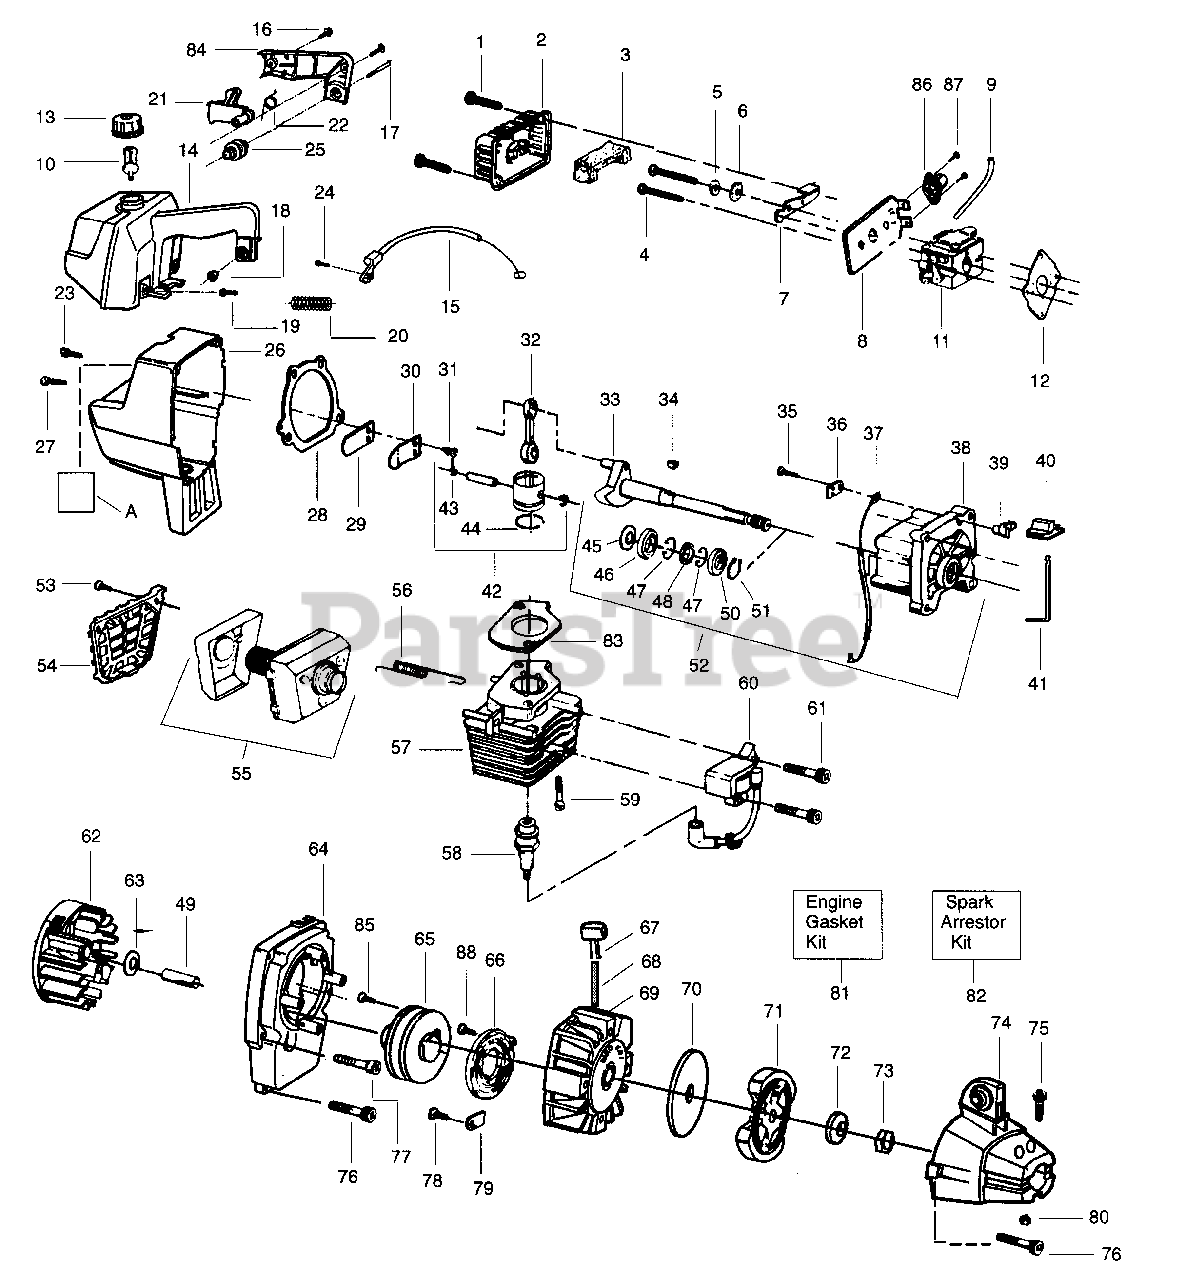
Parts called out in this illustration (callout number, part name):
2	Air Filter Cover
3	Air Filter
6	Wave Washer
7	Choke Shutter
8	MODEL GTI 19
8	MODEL GTI 19T Type 2 & 3
9	Fuel Line
9	MODEL GTI 19T Type 2 & 3
10	Fuel Pick-up Ass'y.
11	WA-199 MODEL GTI 19
11	WA-298A MODEL GTI 19T Type 2 & 3
12	Carburetor Gasket
13	Fuel Cap Ass'y.
14	MODEL GTI 19
14	MODEL GTI 19T Type 2 & 3
15	Throttle Cable Ass'y
16	Screw
20	Rear Isolator Spring
21	Throttle Trigger
22	Throttle Spring
25	Isolator
30	Reed Stop
32	Connecting Rod Ass'y.
33	Crankshaft Ass'y. See Service Ref. 1
34	Flywheel Key
36	Switch Insulator
37	Lead Wire
38	Crankcase Ass'y. (Incl. 46-48 & 50)
39	Switch Ramp
40	Switch Button
41	Switch Spring
42	Piston Kit (Incl. 43,44 & pin)
43	Piston Pin Retainer
44	Piston Ring
46	Inner Bearing
47	Retaining Ring
48	Crankshaft Seal
50	Outer Bearing
51	Crankshaft Retaining Ring
52	Crankcase & Crankshaft Ass'y. (Incl. 33,38 & 46-51)
54	Muffler Guard
55	Muffler Kit
56	Muffler Spring
57	Cylinder
58	Type 2 (CJ-14)
58	Type 3 (RCJ-8Y)
60	Ignition Module Kit
61	Screw
62	Flywheel Ass'y.
64	Fan Housing
65	Starter Pulley (Incl. 85)
66	Starter Spring
67	Starter Handle
68	Rope Kit
69	Pulley Housing Ass'y.
70	Clutch Washer
71	Clutch Ass'y. Kit
74	Clutch Housing
79	Pulley Retainer
81	Engine Gasket Kit (Inc. 12,28,83)
82	Spark Arrestor Kit
83	Cylinder Gasket
84	Handle Cover
86	MODEL GTI 19T Type 2 & 3
87	MODEL GTI 19T Type 2 & 3
88	Screw-Starter Spring MODEL GTI 19T Type 3
